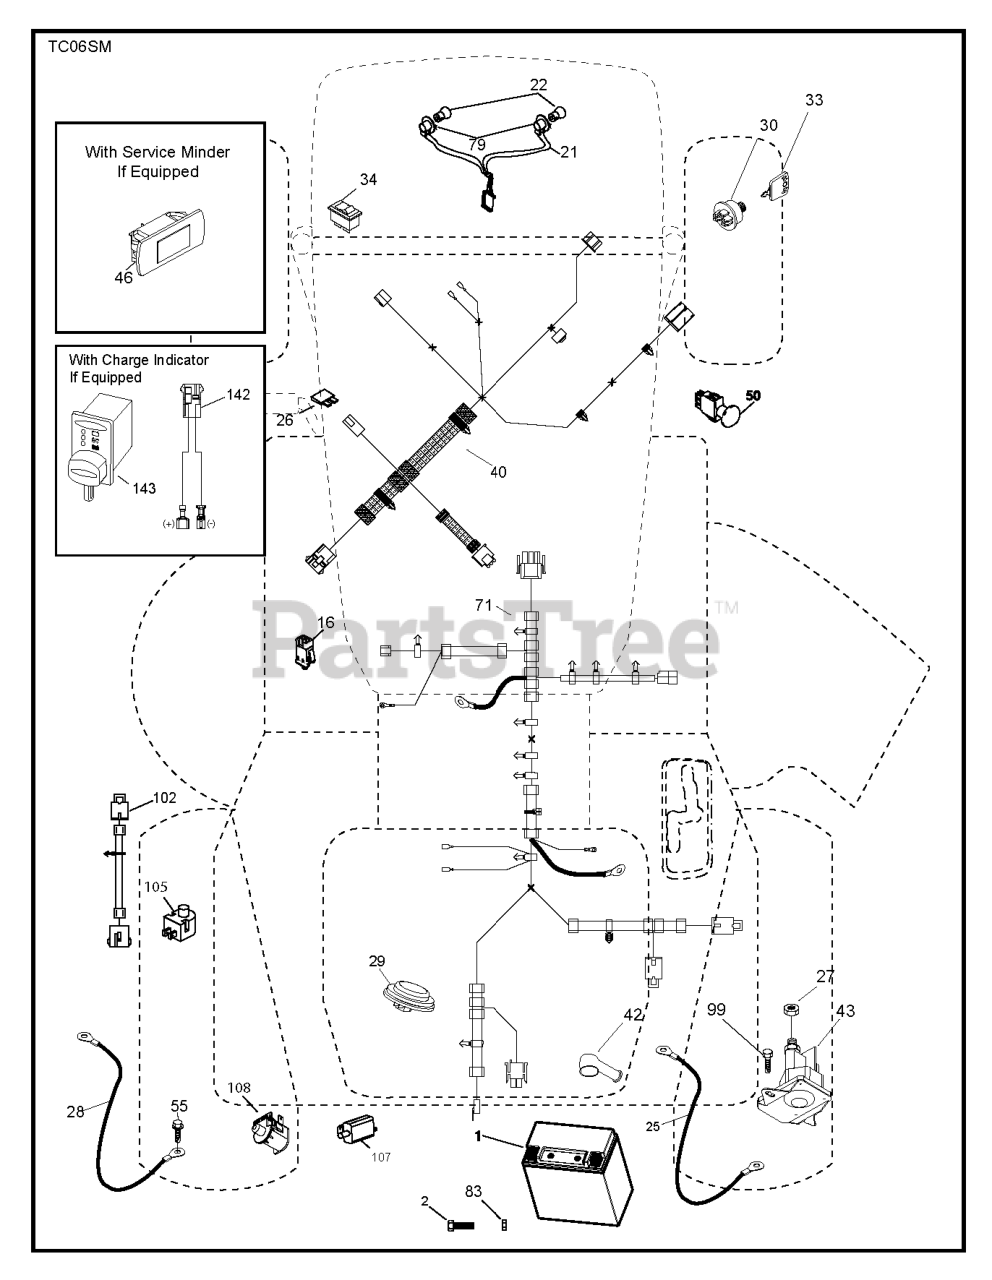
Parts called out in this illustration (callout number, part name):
1	BATTERY BATTERY 14AH 12V LEOC
2	SCREW.HEX.HEAD.CAP.M6 X1.12W
16	SWITCH INTERLOOK PUSH-IN
21	HARNESS.LIGHT W/4152J BULBS
25	CABLE.BATT.8GA.RED9.CRD2.5
26	FUSE 20AMP
27	NUT
28	CABLE.BATT.BLCK10.SLV.CRD2.5
29	SWITCH.SEAT.DELTA.OPC.
30	SWITCH.IGN.DELTA.W.LGH.ROS
33	KEY.CHAIN.BLISTER.PACK.GEN.INT
40	HARNESS.DASH.EL.SRD.CRD.RDY.ST
42	TERMINAL COVER
43	SOLENOID.STARTER.BRASS.PLUNGER
46	GUAGE.SRVCMNDR.HRMTR.
50	SWITCH.PTO.8TERMINAL.STD.BLK
55	SCREW 5/16"
71	HARNESS.CHASS.CRD.TEX.RDY.STRT
79	BULB HOLDER ASM.
83	NUT NUT SQUARE
99	SCREW
102	HARNESS ASSY
105	REVERSE SWITCH
107	.WITCH.FULL BAGGER.INDICATOR
108	SWITCH.SNPMT.NCBT.CRD.MTL.BKPL
142	CHARGE.PORT.PIGTAIL HARNESS
143	CHARGE.PORT
